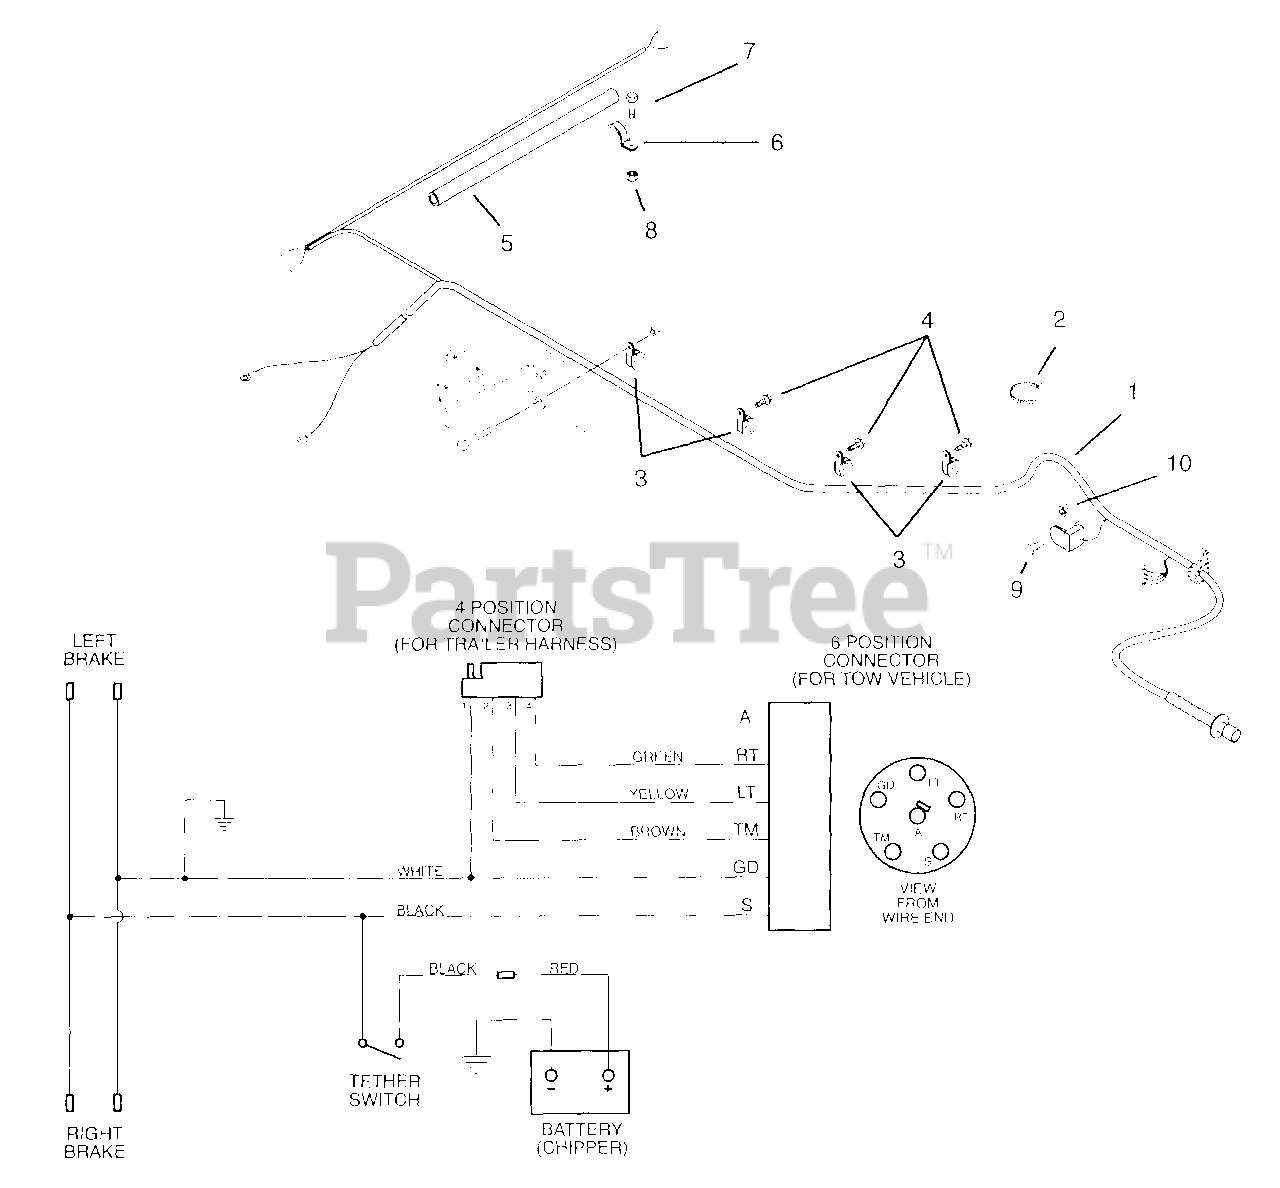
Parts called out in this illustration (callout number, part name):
1	Harness-Wiring Electric Brake
2	Cable Tie
3	Clamp-Cushioned Steel
4	Screw-Tapping .25 x .50 Hex Washer Head
5	Tube-Brake Line Protective
6	Clamp-Steel 1.0
7	Bolt-Hex .38-16 x 1.00 Grade 5
8	Nut-Locking-Center .38-16
9	Bolt-Hex .25-20 x .75 Grade 5
10	Nut-Locking-Center .25-20
